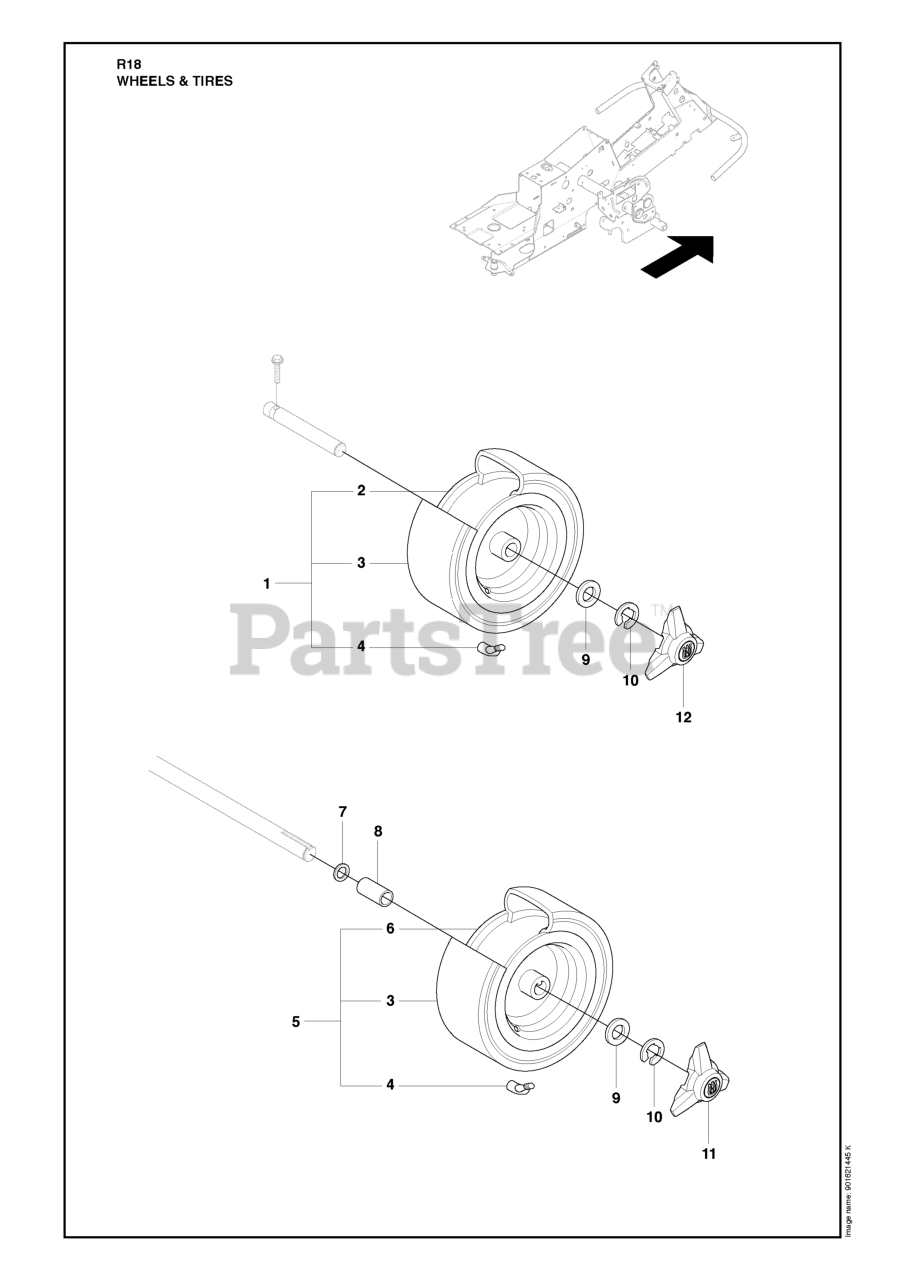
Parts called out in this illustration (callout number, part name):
3	TIRE
4	VALVE
7	TIRE
8	VALVE
10	SPACE SLEEVE
12	RETAINING RING
